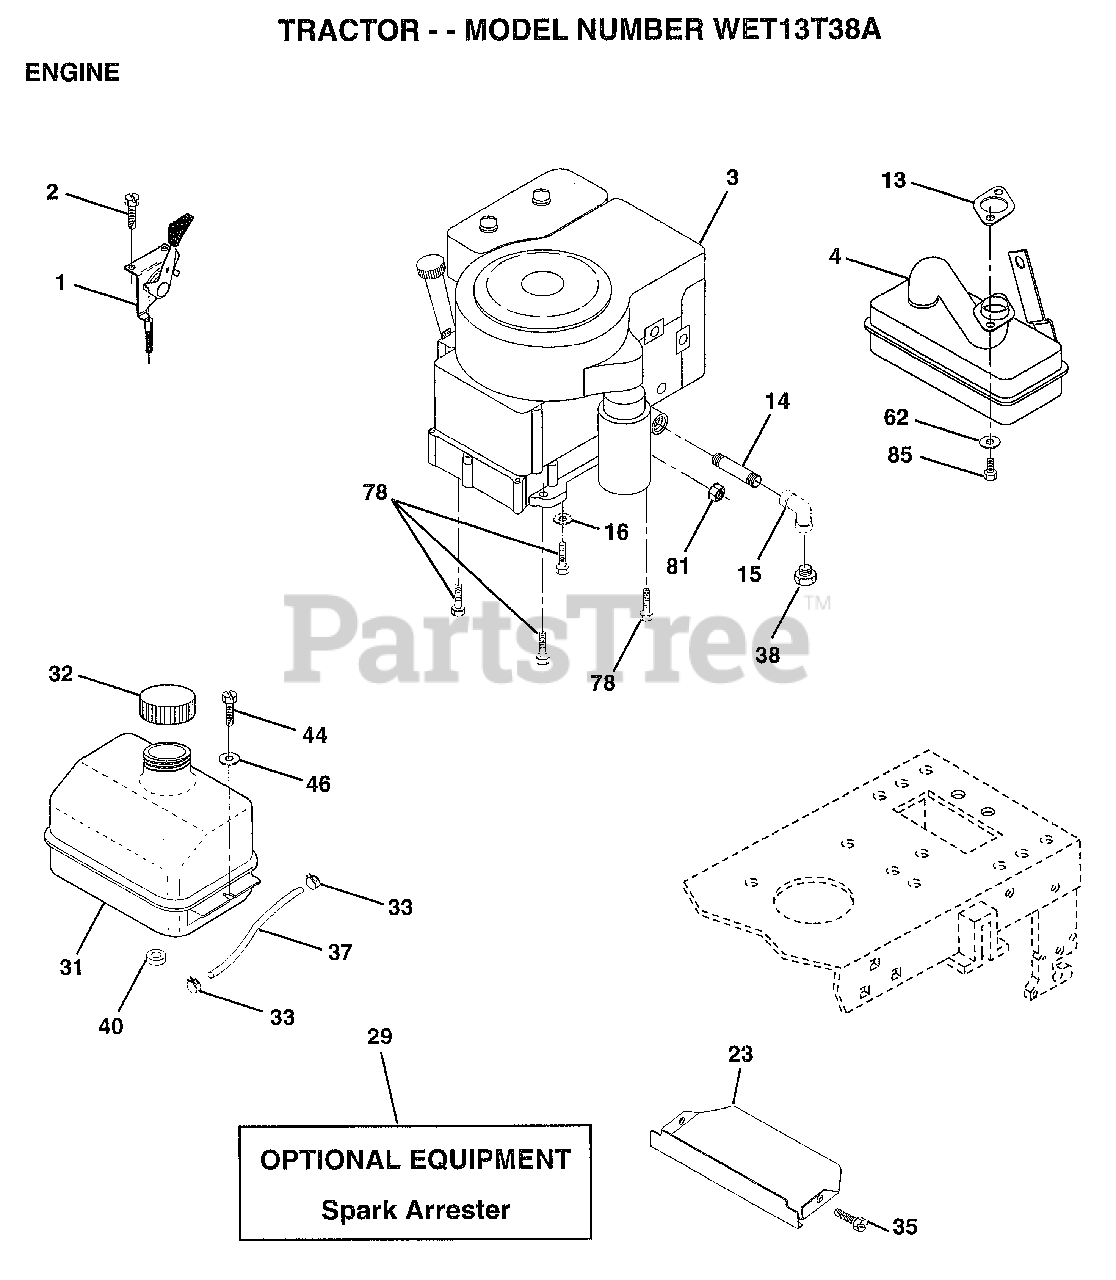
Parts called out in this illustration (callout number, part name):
1	CONTROL-THROT/CHO
2	SCREW LT
4	MUFFLER TEC. 13HP
13	GASKET ENG 1 313 LD TIN PLATED
14	PIPE NIPPLE
15	ELBOW
16	LOCKWASHER
23	SHIELD.BRN/DBR.GD
31	TANK.FUEL.LT.
32	CAP ASM FUEL
33	HOSE CLAMP
35	SCREW
37	LINE FUEL
44	SCREW HEX CRT
46	WASHER
62	LOCKWASHER
78	SCREW
81	NUT
85	SCREW HEX HD CAP
